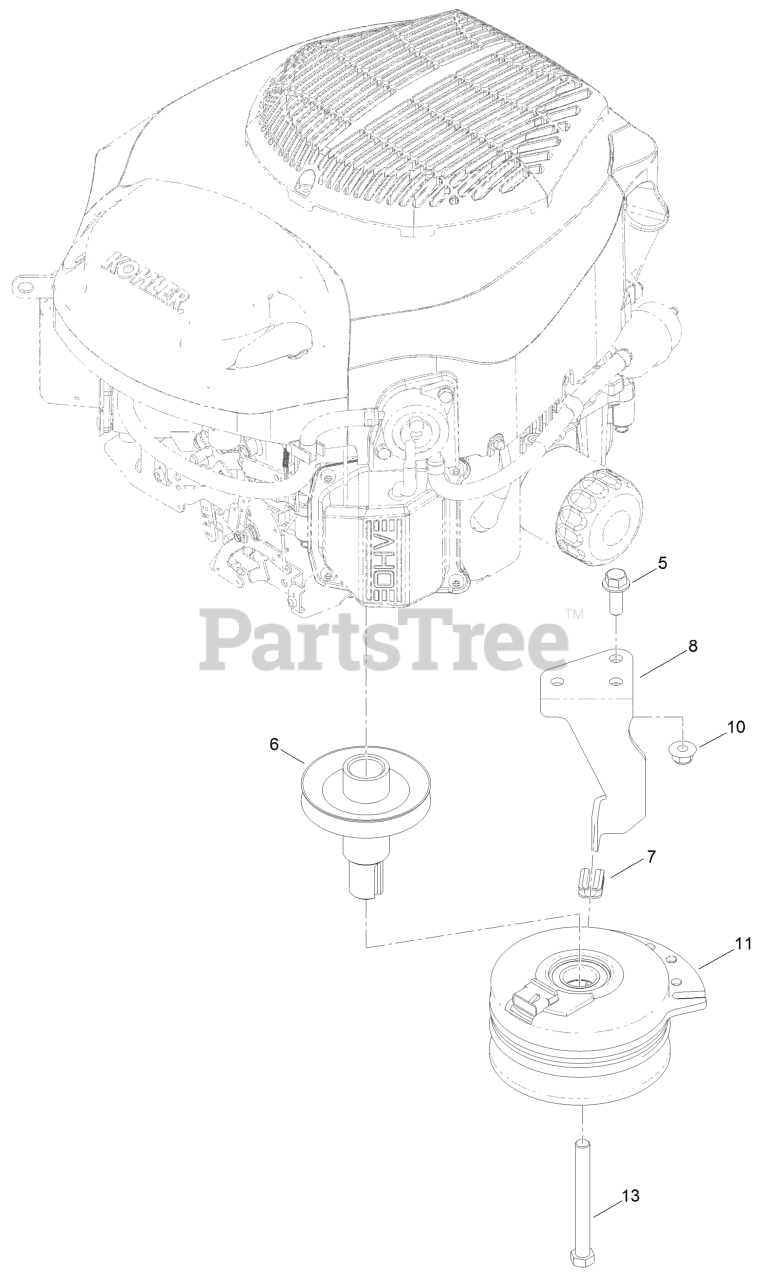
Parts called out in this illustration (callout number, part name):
5	SCREW-HHF 3/8-16 X 1
6	PULLEY-ENGINE
7	ISOLATOR-CLUTCH
8	STOP-CLUTCH (NARROW)
10	NUT-HF, NI
11	CLUTCH-ELECTRIC
13	PIN-ROLL, SLOTTED
